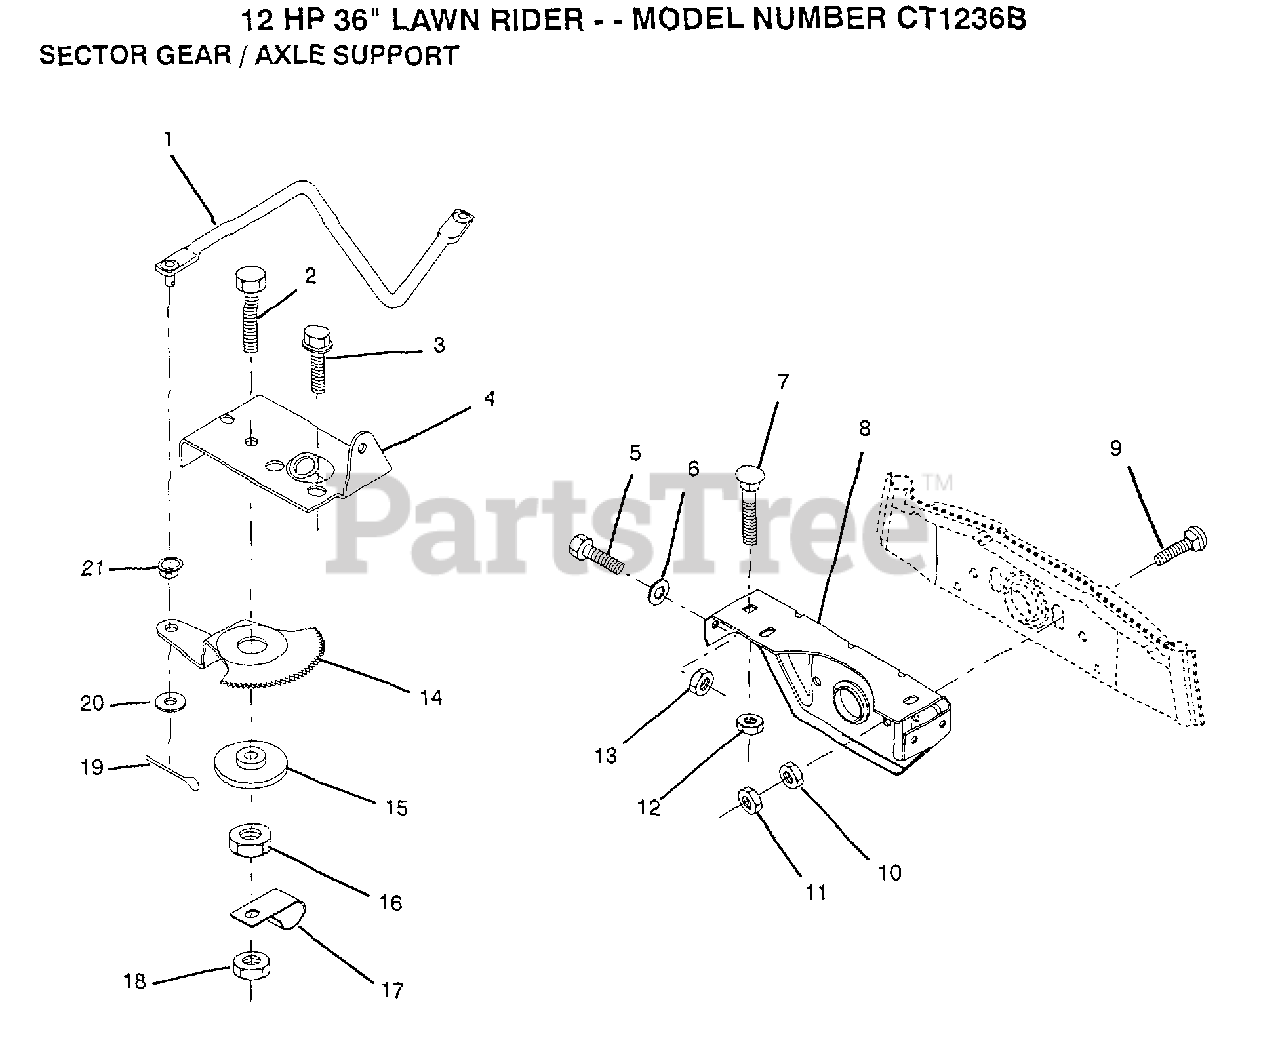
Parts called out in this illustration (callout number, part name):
2	"BOLT,HEX"
3	SCREW LT
4	"PLATE,STR SUPT"
5	BOLT
6	WASHER
7	BOLT
8	"SUPT,FRT AXLE"
9	BOLT
10	NUT.HEX.3/8-16UNC
11	LOCKNUT
14	GEAR SECTOR
15	BUSHING
16	NUT
17	CLIP INSULATOR
18	NUT LTV
19	COTTER PIN
20	WASHER
21	BUSHING.DRAGLINK
